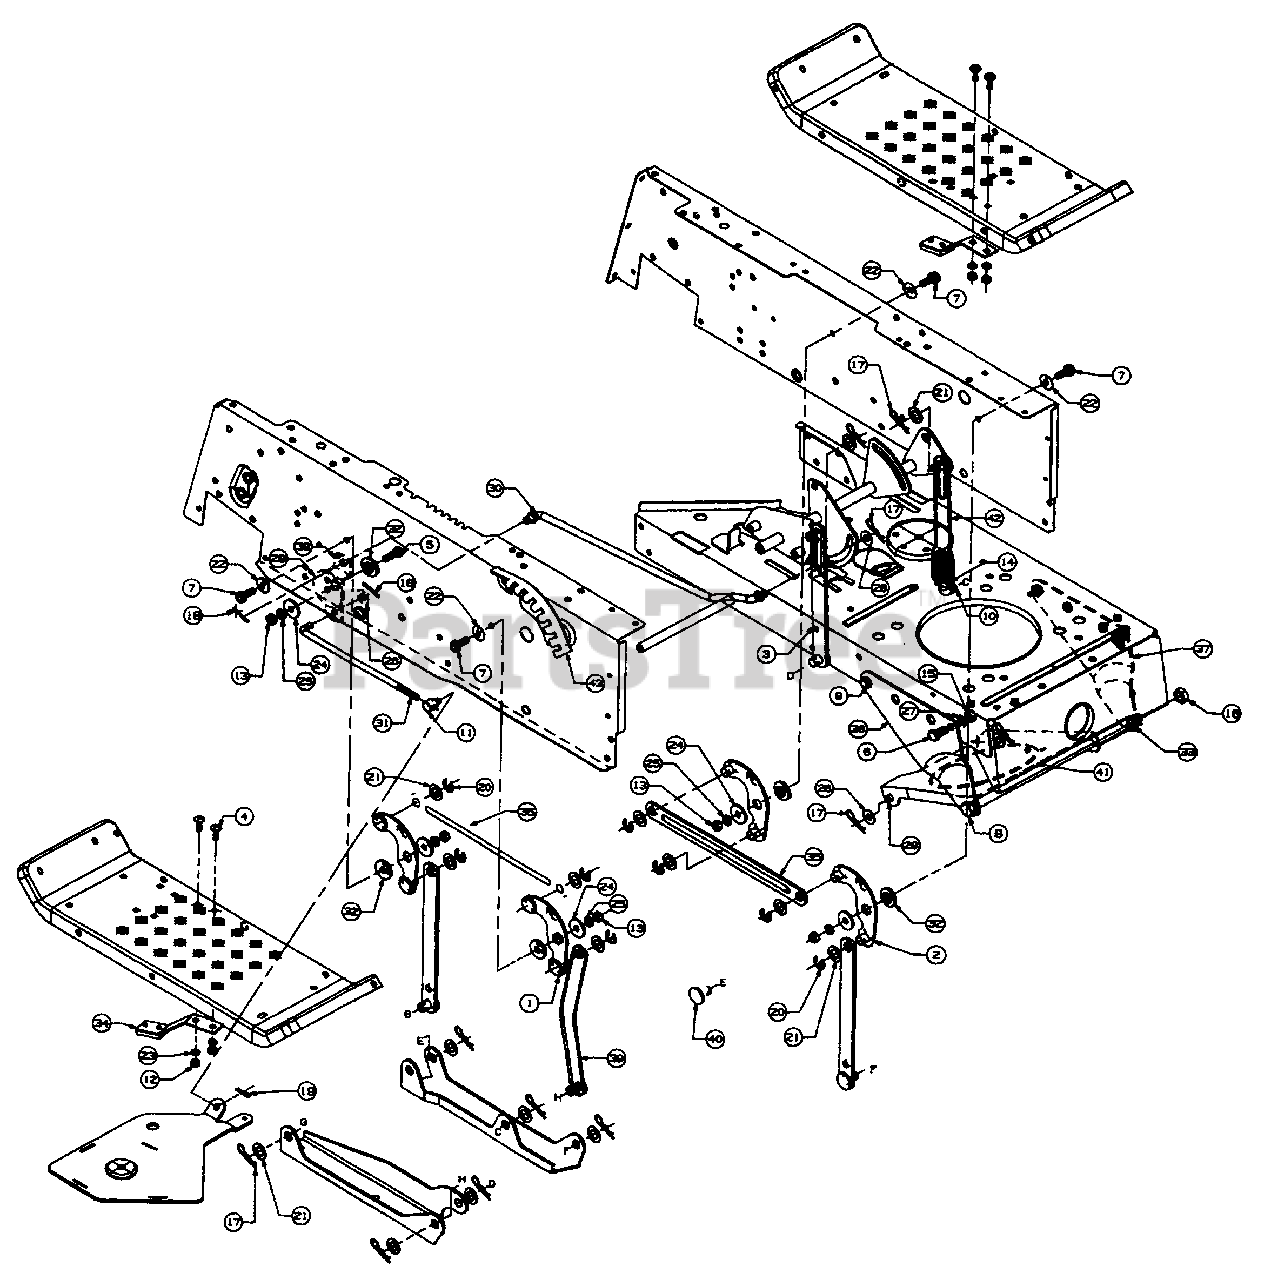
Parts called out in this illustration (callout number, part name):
1	Pivot Link Ass'y. - R.H.
2	Pivot Link Ass'y. - L.H.
3	Deck Link Lift Ass'y.
4	Carr. Bolt 1/4-20 x .62" Lg.
5	Hex Bolt 5/16-18 x 1" Lg. (Gr. 5)
6	Hex Bolt 3/8-24 x .75" Lg. (Gr. 5)
7	Hex Scr. 5/16-18 x .87" Lg.
8	Hex Bolt 1/2-20 x 13" Lg. (Gr. 5)
9	Hex Wash. Hd. Scr. 5/16 x .5" Lg.
10	Adjuster Lift Link
11	Ferrule
12	Hex Nut 1/4-20 Thd.
13	Hex Nut 5/16-18 Thd.
14	Hex Nut 1/2-20 Thd. (Gr. 5)
15	Hex Nut 3/8-24 Thd.
16	Hex Ins. Jam L-Nut 1/2-20 Thd.
17	Hairpin Clip
18	Cotter Pin 1/8" Dia. x 1" Lg.
19	Hairpin Clip
20	"E"-Ring
21	Fl-Wash. .531" I.D. x .93" O.D.
22	Bell-Wash. .325" I.D. x .93" O.D.
23	L-Wash. 1/4" I.D.
24	Fl-Wash. .344" I.D. x 1-1/8" O.D.
25	L-Wash. 5/16" I.D.
26	Fl. Wash. 3/8" I.D. x .87" O.D.
27	L-Wash. 3/8" I.D.
28	Fl-Wash. .34" I.D. x 2.25" O.D.
29	Shaft 3/8" Dia. x 9.34" Lg.
30	Deck Disengagement Rod
31	Deck Disengagement Rod
32	Shld. Spacer
33	Spacer .515" I.D. x 3.6" Lg.
34	Blade Brake Ass'y.
43	Index Brkt
